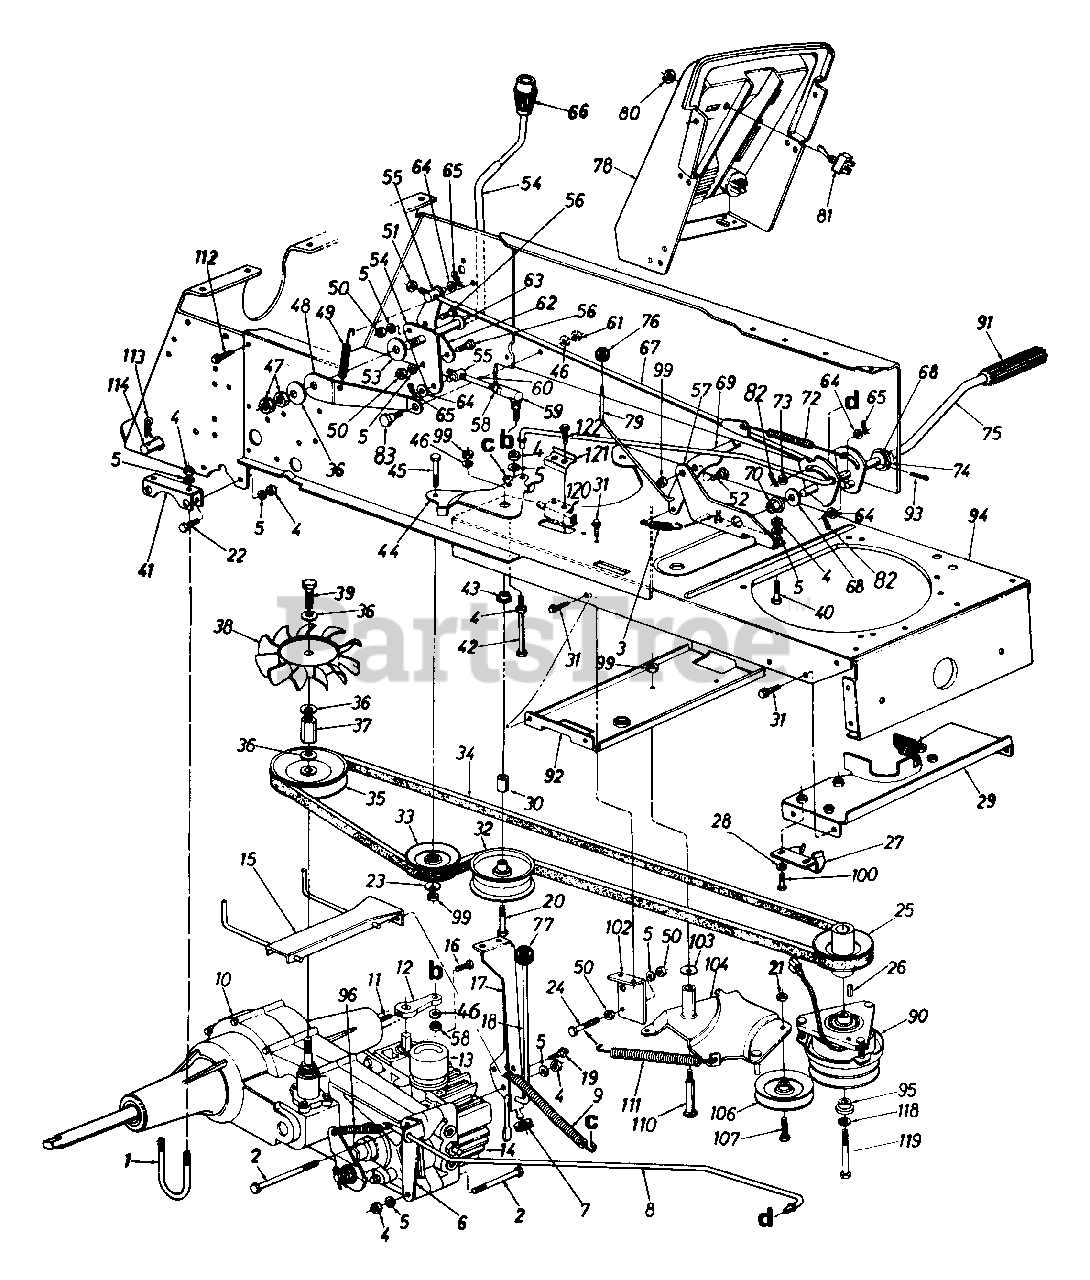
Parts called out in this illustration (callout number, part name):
1	U-Bolt 5/16-18 x 3.25" Lg.
2	Hex Patch Bolt 5/16-18 x 4.5" Lg. (Gr. 5)
3	Ext. Spring .5" O.D. x 1.55"
4	Hex Nut 5/16-18 Thd.
5	L-Wash. 5/16" I.D.
6	Brake Rod Guide Brkt.
7	Rubber Wash. .33" I.D. x .87"
9	Ext. Spring .62" O.D. x 6.12" Lg.
11	Set Screw 5/16-24 x .38" Lg.
12	Pintle Shift Lever
13	Reservoir
14	Hydrostatic Pump
15	Belt Guard Ass'y.
16	Hex Bolt 5/16-18 x 4.5" Lg. (Gr. 5)
17	Transaxle Torque Bracket
18	Transaxle Control Rod
19	Hex Wash. Hd. B-Tap Scr. 5/16-18
20	Hex Bolt 3/8-16 x 2.75" Lg.
21	Hex Cent. Lock Nut 3/8-16 Thd.
22	Hex Bolt 5/16-18 x .75" Lg. (Gr. 5)
23	Fl-Wash. .385" I.D. x .87" O.D.
24	Hex Bolt 5/16-24 x 1.75" Lg.
25	Engine Pulley
26	Sq. Key 1/4 x 1" Lg.
29	Belt Keeper Brkt. Ass'y.
30	Spacer .375" I.D. x .75" Lg.
31	Hex Wash. Hd. TT-Tap Scr. 1/4-20 x .5" Lg.
32	Fl-Idler Pulley 3.25" Dia.
33	V-Belt Idler
34	V-Belt
35	Transmission Pulley 4.25" O.D.
36	Bell-Wash. .56" I.D. x 1.5"
37	Fan Adapter Nut 9/16-18 Thd.
39	Hex Bolt 9/16-18 x .5" Lg.
40	Hex Bolt 5/16-18 x .75" Lg.
41	Transaxle Mtg. Bracket
42	Hex Bolt 5/16-18 x 2.75" Lg.
43	Shld. Spacer .625" I.D.
44	Clutch Idler Bracket
45	Hex Bolt 3/8-16 x 1.5" Lg.
46	L-Wash. 3/8" I.D.
47	Hex Jam Nut 1/2-20 Thd.
48	Speed Control Rod Torque Brkt.
49	Ext. Spring 2.5" Lg.
50	Hex Nut 5/16-24 Thd.
51	Hex Jam Nut 3/8-24 Thd.
52	Shld. Bolt .50" Dia. x .170"
53	Fiber Washer .54" I.D. x 1.75"
54	Speed Control Handle Ass'y.
55	Ferrule 3/8-24 Thd.
56	Hex Bolt 5/16-24 x .62" Lg.
57	Foot Pedal Mtg. Brkt.
58	Hex Nut 3/8-24 Thd.
59	Ball Joint Ass'y.
60	Control Rod 3/8-24 x 3.75" Lg.
61	Hex Nut 3/8-16 Thd.
62	Speed Selector Handle Brkt.
63	Fl-Wash. .531" I.D. x 1.25" O.D.
64	Fl-Wash. .385" I.D. x .62" O.D.
65	Internal Cotter Pin
67	Neutral Return Rod
68	Fl-Wash. .64" I.D. x 1.24" O.D.
69	Parking Brake Lock Brkt.
70	Hex Flange Brg. .634" Dia.
72	Extension Spring 8" Lg.
73	Fl-Wash. .344" I.D. x .62" O.D.
74	Flange Bearing w/Flats
75	Foot Pedal Ass'y.
76	Ball Knob Brake
77	Ball Knob 1/4-20 Thd.
78	Dash Panel Ass'y.
79	Parking Brake Link
80	Hex Nut 1/2-27 Thd.
81	Toggle Switch
82	Cotter Pin 3/32" Dia. x 1.0" Lg.
83	Shld. Bolt .5" Dia. x .212"
90	Electric Clutch
91	Foot Pad
92	Deck Idler Support Brkt.
93	Cotter Pin 1/8" Dia.
94	Lower Frame
95	Shoulder Spacer
96	Ext. Spring 3.675" Lg.
99	Hex Cent. L-Nut 3/8-16 Thd.
100	Hex Bolt 5/16-18 x .75" Lg. (Gr. 5)
102	Parking Brake Mtg. Brkt.
103	Bell-Wash. .380" I.D. x .88" O.D.
104	Idler Brkt. Deck Ass'y.
106	V-Belt Idler
107	Hex Bolt 3/8-24 x 1.5" Lg.
110	Shld. Bolt .498" Dia. x 2.05"
111	Ext. Spring 4.0" Lg.
112	Hex Wash. AB-Tap Scr. 5/16 x .75" Lg.
113	Hitch Pin Clip
118	L-Wash. 7/16" I.D.
119	Hex Bolt 7/16-20 x 3.75" Lg.
120	Safety Switch
121	Switch Plate
122	Torx Hd. Mach. B-Tap Scr.
